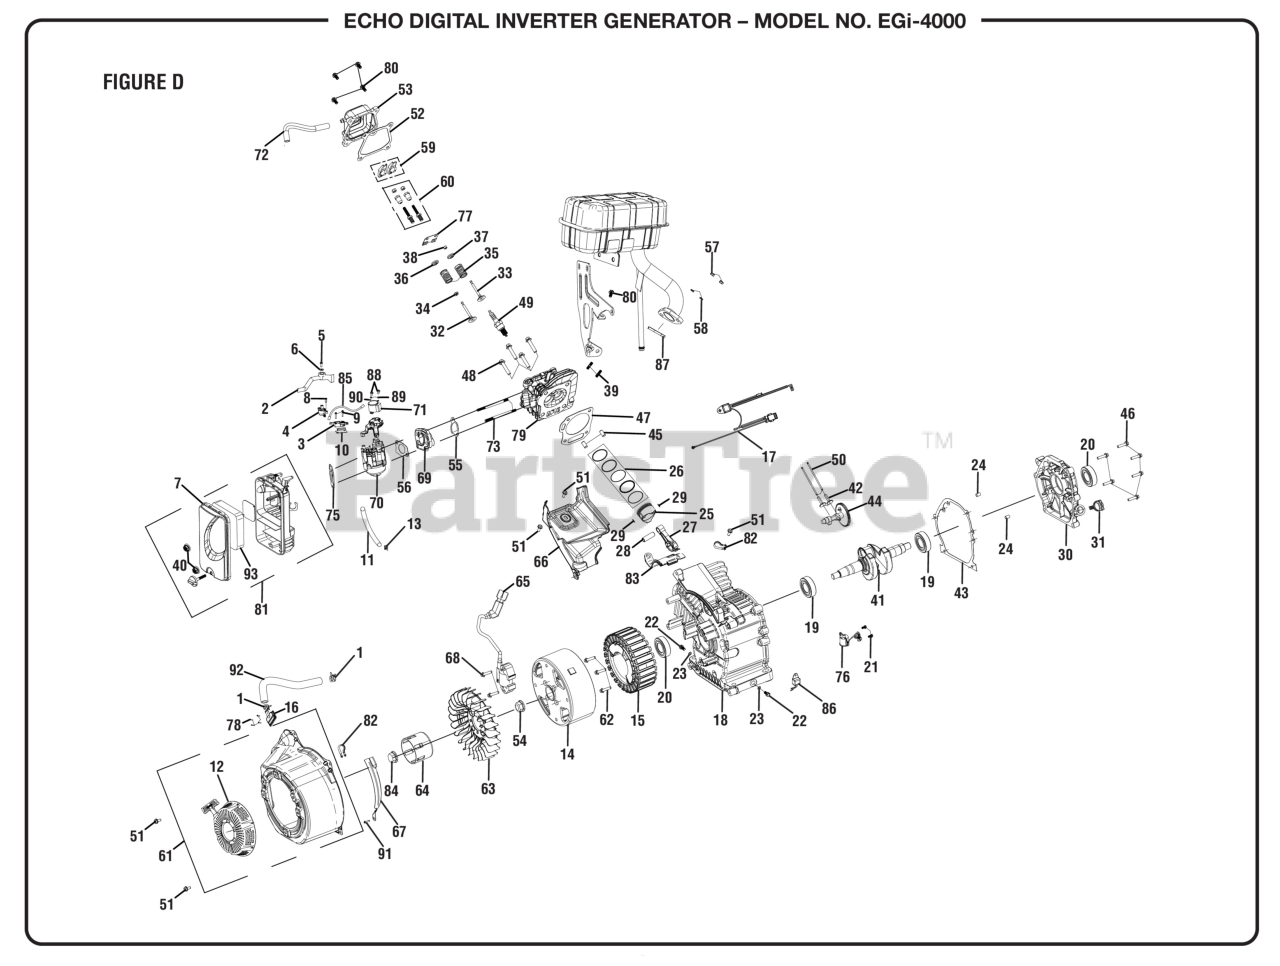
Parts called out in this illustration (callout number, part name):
1	CLAMP, FUEL HOSE
2	LEVER, CONTROL
3	SWITCH, ENGINE STOP
4	VALVE, FUEL
5	BOLT, PHILLIPS
8	BOLT, PHILLIPS PAN HEAD
9	SCREW, PHILLIPS PAN HEAD
10	BRACKET, ENGINE STOP
11	HOSE, FUEL
12	COVER, ENGINE RECOIL
13	CLAMP, FUEL HOSE
15	STATOR, W/ DC COIL
16	VALVE, PAIR
17	WIRE HARNESS, CO SHUTDOWN
18	CRANKCASE
19	BEARING, BALL
20	SEAL, OIL
22	BOLT, DRAIN PLUG
23	Drain Plug Bolt
24	DOWEL PIN, CASECOVER
26	SET, PISTON SCRAPER RING
27	ASSY., CONNECTING ROD
28	RING, PISTON
29	CLIP, PISTON
30	COVER, CRANKCASE
31	DIPSTICK
32	VALVE, INTAKE
33	VALVE, EXHAUST
34	RETURNER, INTAKE VALVE
35	SPRING, VALVE
36	SEAT, INTAKE VALVE SPRING
37	SEAT, EXHAUST VALVE SPRING
39	BOLT, STUD
41	ASSY., CRANKSHAFT
42	LIFTER, VALVE
43	GASKET, CRANKCASE
44	ASSY., CAMSHAFT
45	PIN, DOWEL
47	GASKET, CYLINDER HEAD
49	PLUG, SPARK
50	PUSH, ROD
52	GASKET, VALVE COVER
53	COVER, VALVE
55	GASKET, INTAKE
56	GASKET, CARBURETOR
58	WASHER, SPRING
59	ASSY., ROCKER
60	ADJUSTER, ROCKER ARM
61	ASSY., RECOIL STARTER
63	FAN, RECOIL STARTER
64	PULLEY, STARTER
65	MODULE, IGNITION
69	INSULATOR, CARBURETOR
70	ASSY., CARBURETOR
71	MOTOR, STEPPER
72	TUBE, BREATHER
73	BOLT, STUD
74	CLIP,FUEL LINE
75	SPACER, CARBURETOR
76	SWITCH, OIL LEVEL
77	PLATE, PUSH ROD GUIDE
79	CYLINDER HEAD
81	ASSY., AIR CLEANER
82	CLIP, FUEL LINE
85	WIRE, FLAMEOUT
86	AMPLIFIER
89	WASHER, SPRING
90	WASHER, FLAT
92	HOSE, PAIR VALVE
93	FILTER, AIR
